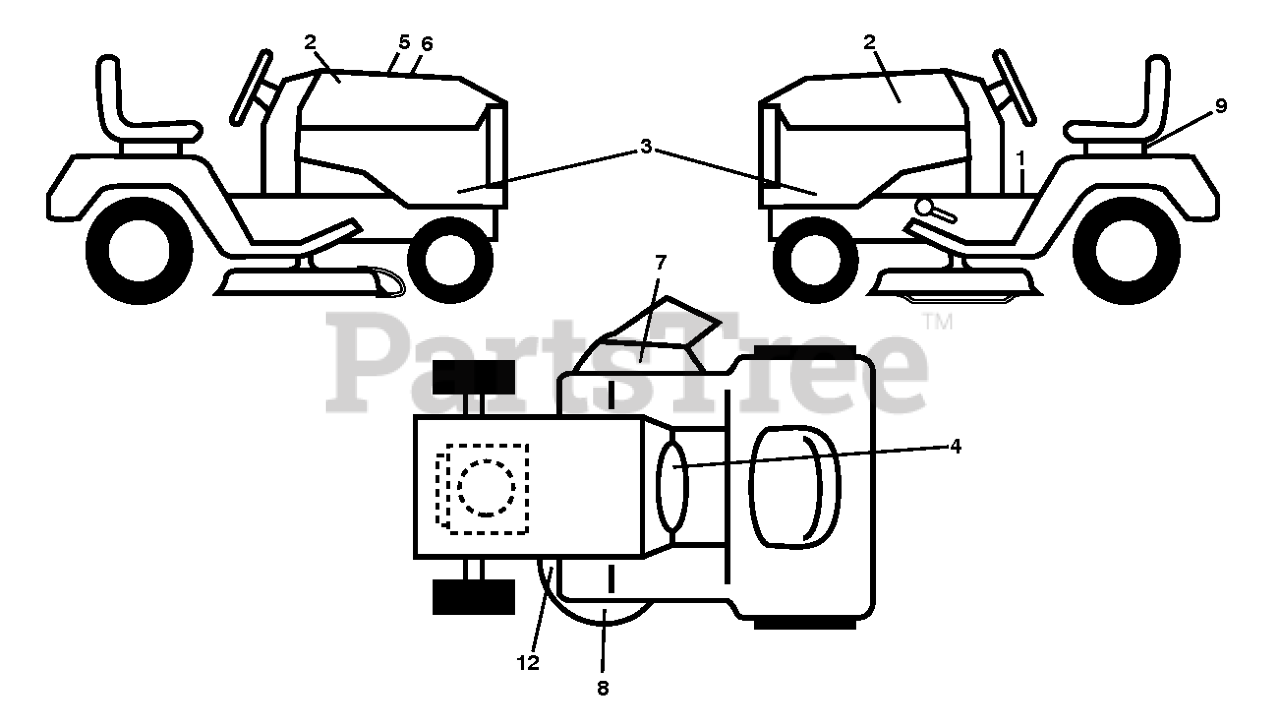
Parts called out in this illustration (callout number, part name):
1	DECAL.FENDER.WARNING.ENGLISH
2	DECAL.BADGE.170MM.TEXTLOGO.
3	DECAL.SIDE.PANEL.YTH18K46
4	DECAL, WARNING SPARK ARRESTOR
5	DECAL.WARNING.CUST.RESP.E85.
6	DECAL.RPL.KAW.FR.TLW.46E.K46L
7	DECAL, DECK DEFLECTOR, WARNING
9	DECAL BTRY SYMBOLS
12	DECAL.V-BELT.SCH.42/46"MEC/ELE
